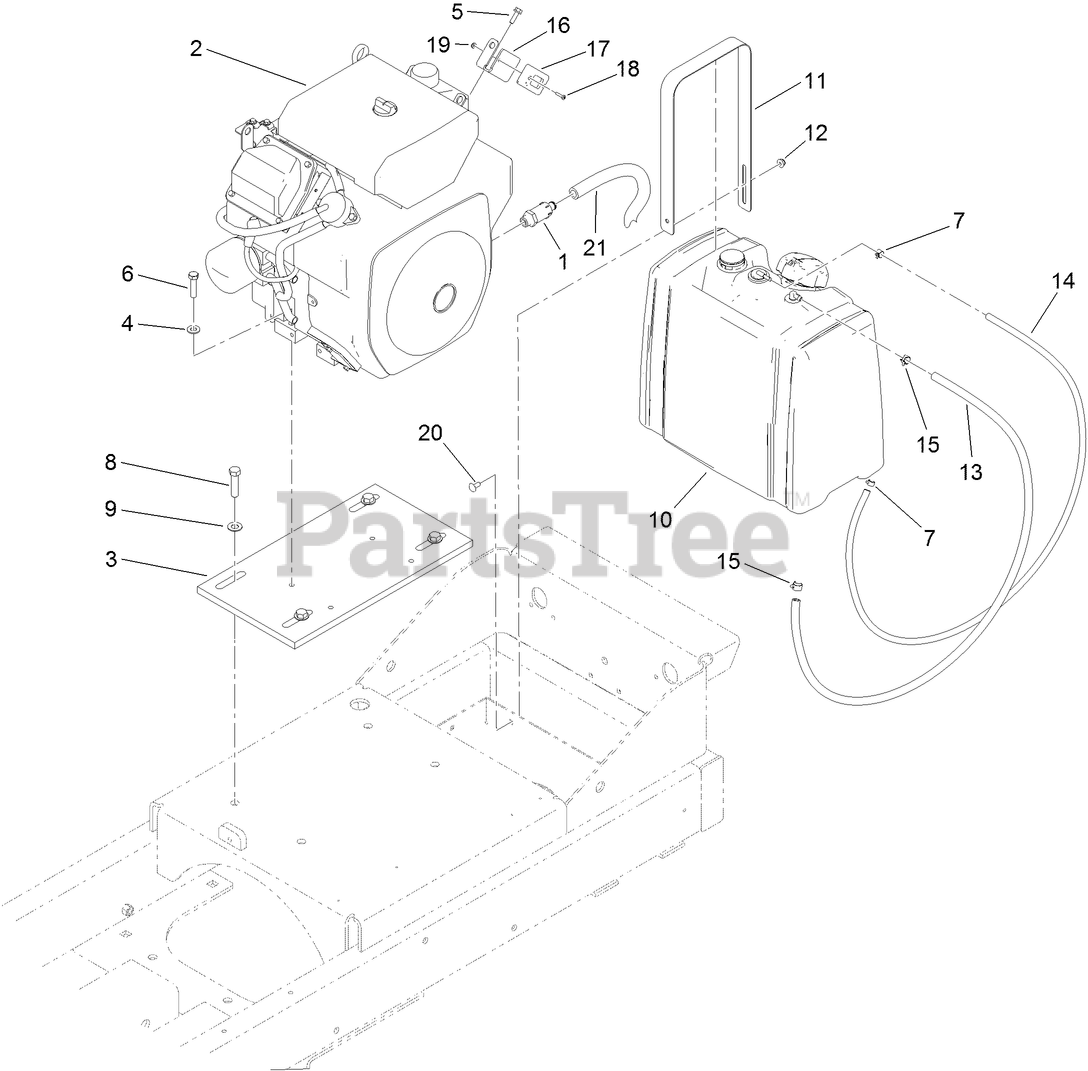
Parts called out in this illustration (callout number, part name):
1	VALVE-DRAIN, OIL
3	PLATE-ENGINE
4	WASHER-FLAT
5	SCREW-HHF
6	SCREW-HH
7	CLAMP-HOSE
8	SCREW-HH
9	WASHER-FLAT
10	FUEL TANK ASM
11	STRAP-HOLD DOWN, TANK
12	NUT-HF
13	HOSE-FUEL
14	HOSE-LP
15	CLAMP-HOSE
16	BRACKET-HOURMETER
17	HOURMETER-INDUCTIVE
18	SCREW-PPH
19	NUT-HEX
20	SCREW-CARR
